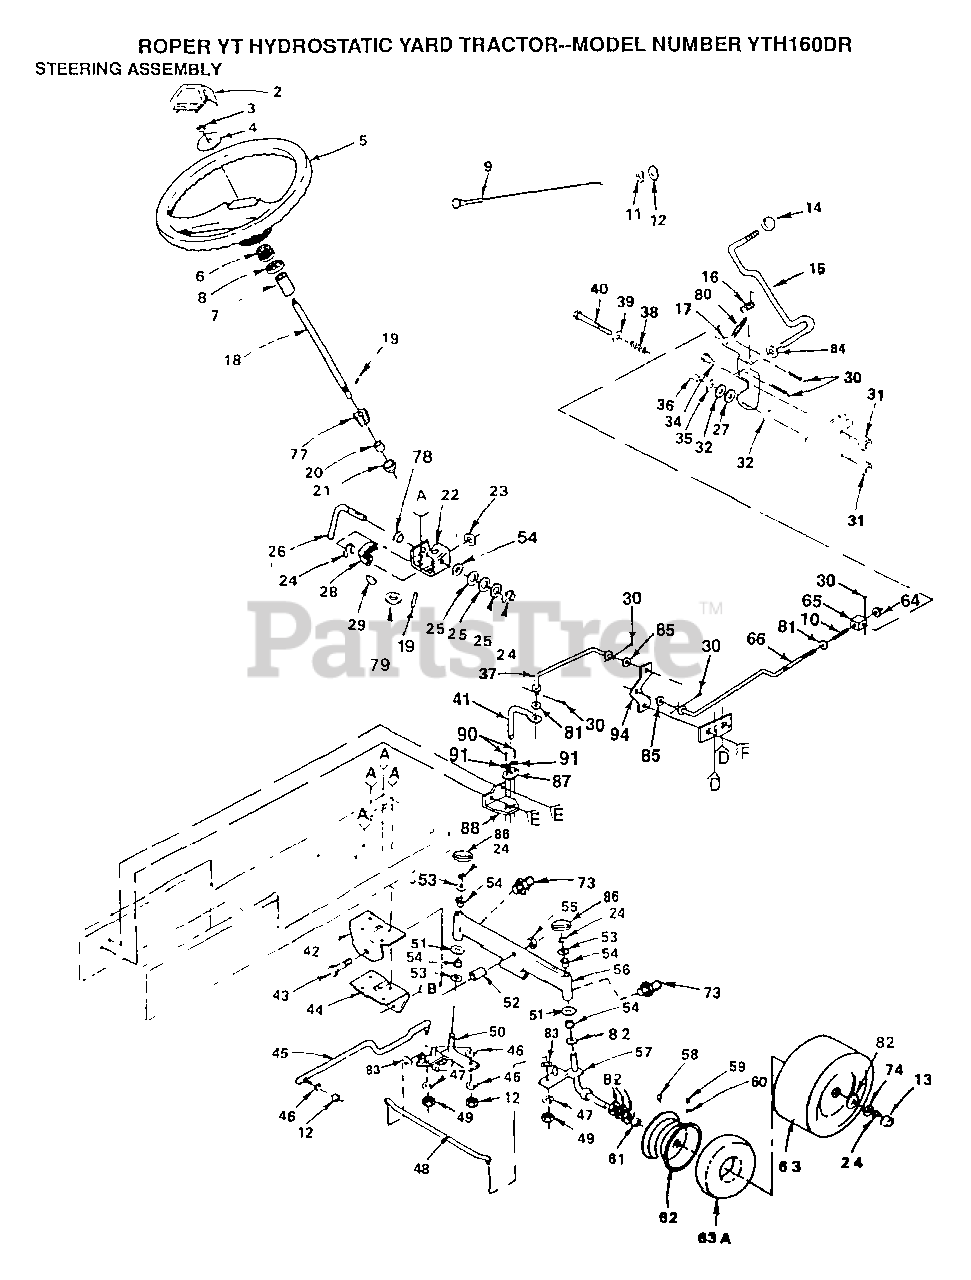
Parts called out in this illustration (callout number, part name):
2	INSERT STEERING
6	ADAPTER LT
10	SPRING GTV
11	LOCKWASHER
13	HUB CAP
14	KNOB.DUCKHEAD.1/2
15	ROD CONTROL
16	SPRING TORSION
17	BRKT CONTROL HYT
18	STEERING SHAFT T
20	SHAFT SPACER LT
21	BUSHING
23	WASHER D
24	RING
25	WASHER .T
26	ROD STEERING T
27	WASHER HYT
28	GEAR.SECTOR.HYT
29	KEY-WOODRUFF LT
30	COTTER PIN
32	WASHER FRIC HYT
34	BOLT HYT
35	WASHER D
36	SPACER HYT
37	LINK CONTROL
38	SPRING HYT
39	WASHER
40	BOLT - HEX 3/8 - 16 X 3
41	ARM ASM PUMP
42	SUPPORT-SADDL T
43	BOLT LT
44	SUPPORT.SADDLE.FT
45	LINK-DRAG LT
46	LOCKWASHER
47	LOCKWASHER
48	ROD TIE
49	NUT.LOCK.5/16-24
50	SPINDLE-LH LT
51	WASHER
52	BEARING
53	WASHER .T
54	COL. SRTG. BEAR.
55	"NUT-LOC,FLANGE LT"
56	FRONT AXLE
58	FITTING LT
59	VALVE STEM LT
60	VALVE CAP
61	"FLANGE, BEARING"
63A	TUBE.5.3/4.5/6
64	NUT
65	TRUNION HYT
66	ROD ADJ CONTROL
73	ZERK M
74	WASHER
77	GEAR PINION T
78	NYLINER T
80	SPRING.RETAINER
81	WASHER T
82	WASHER
83	WASHER M
84	WASHER
85	WASHER T
86	CAP
87	GUIDE CONTROL
88	BRKT
90	SCREW
91	WASHER
94	BELLCRANK
